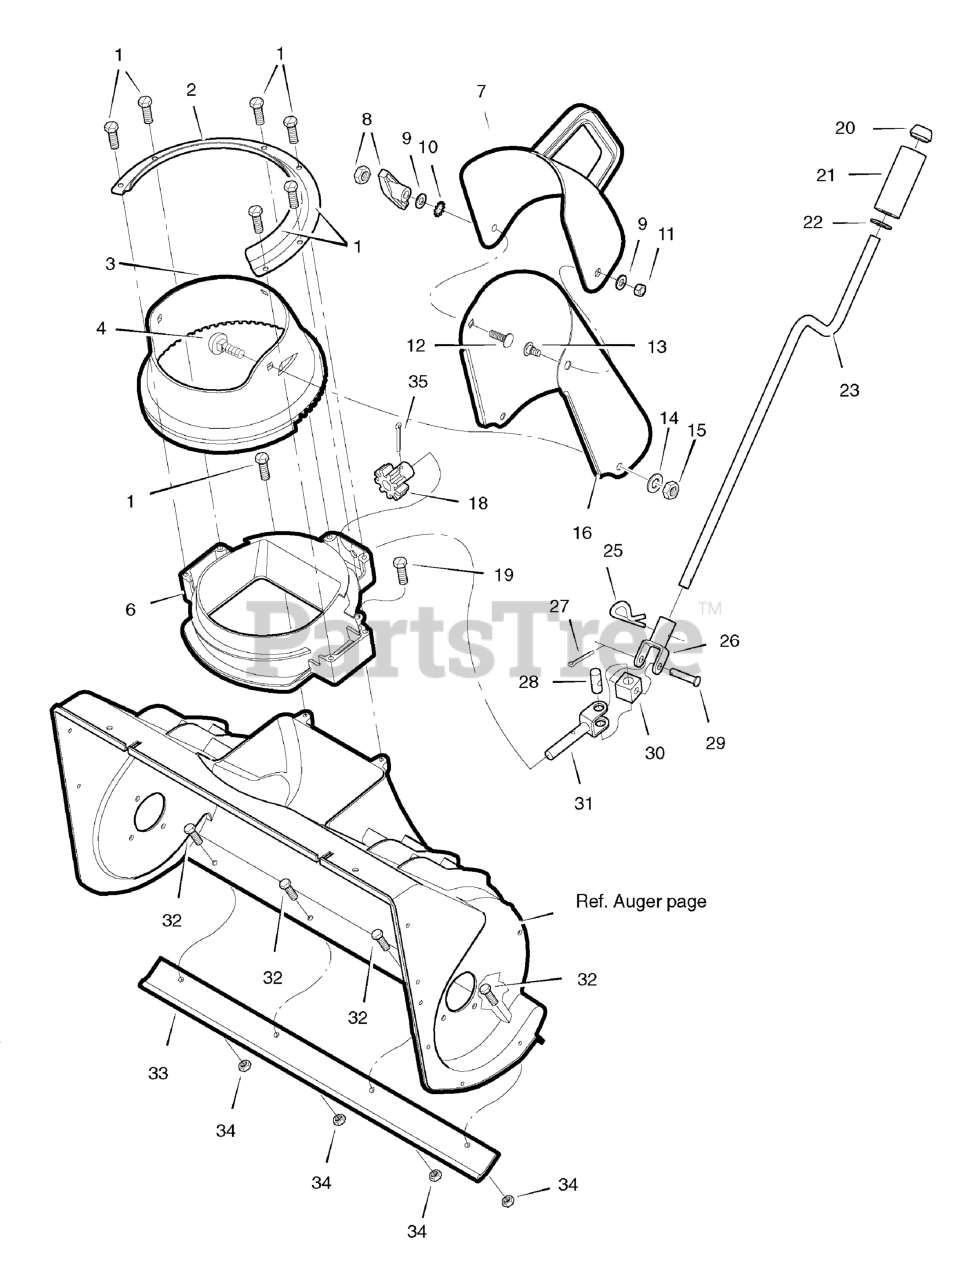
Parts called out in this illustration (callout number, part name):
1	SCREW, 1/4 - 14
2	RETAINER, Chute Ring
3	RING, Chute
4	BOLT, Carriage, 5/16 - 18 x 3/4
6	NECK, Chute
7	CHUTE, 22" Upper
9	WASHER
10	LOCKWASHER, Shakeproof
11	LOCKNUT, Hex, 5/16 - 18
12	BOLT, Carriage, 5/16 - 18
13	BOLT, Upper Chute
14	WASHER
15	NUT
16	CHUTE, Lower
18	GEAR, 9-Tooth
19	SCREW, 1/4 - 14 x 3/4
20	NUT, Push
21	KNOB, Sleeve
22	WASHER
23	CRANK, Chute Rotation
25	PIN, Hair
26	YOKE ASSEMBLY, Adapter
27	PIN, Cotter
28	PIN, Universal Joint
29	PIN, Clevis
30	HOUSING, Universal
31	ROD, Lower Crank
32	SCREW, 1/4 - 20 x 3/4
33	BLADE, Scraper
34	LOCKNUT, Hex, 1/4 - 20
35	PIN, Cotter
